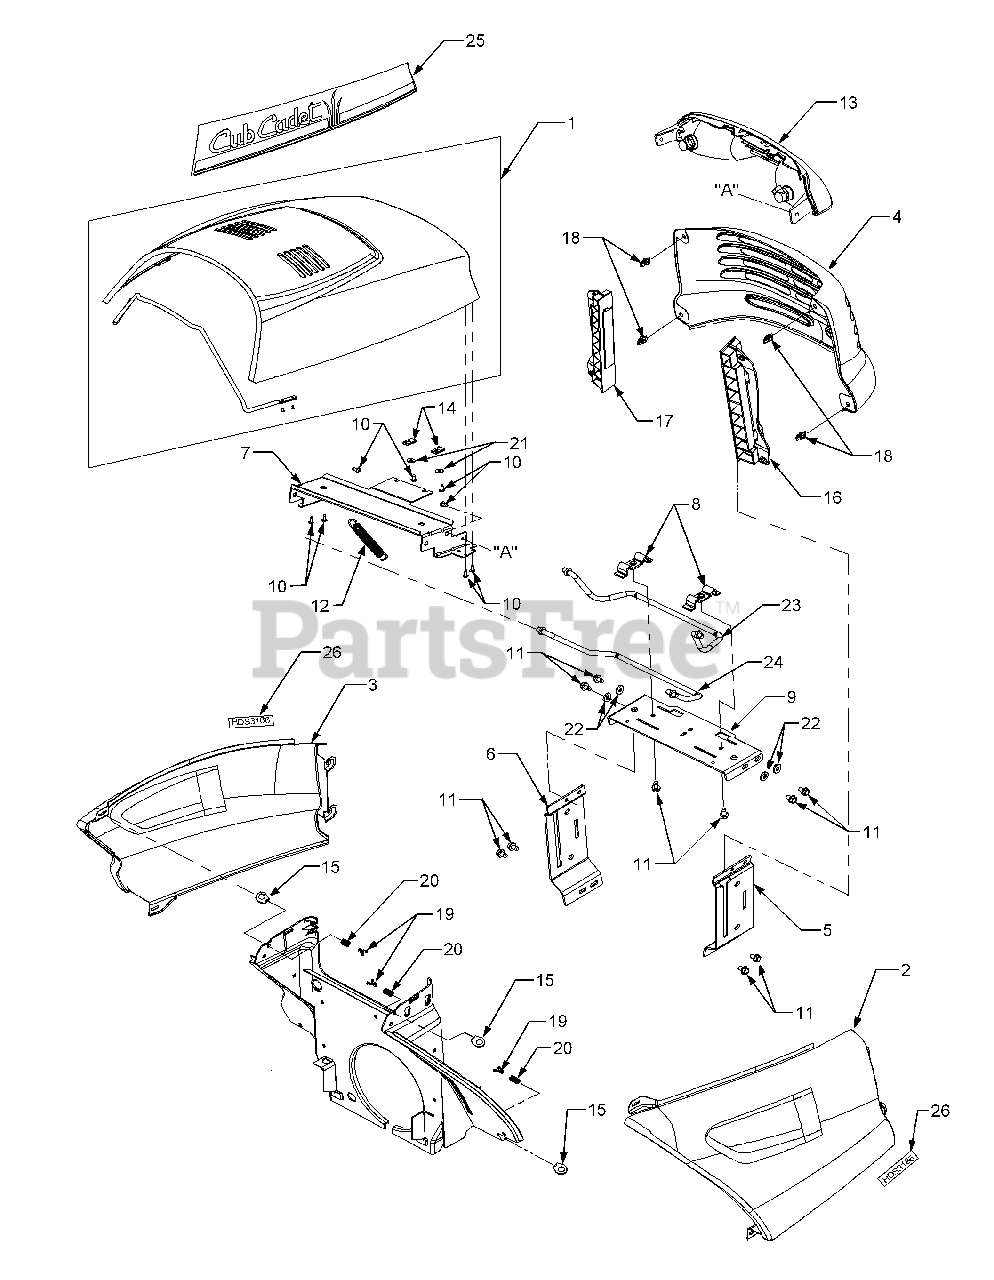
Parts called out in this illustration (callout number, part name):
1	Hood w/Support Rod Assembly
10	Screw, Truss Hd, Tapp, #10-16 x .5
11	Screw, Hex Wash. Hd. Tapp 5/16-18 x .5
12	Spring, Extension
13	Headlight Assembly
14	Nut, U-type Speed, #10
15	Latch, 1/4 Turn
16	Mount, Side Panel/Grille RH
17	Mount, Side Panel/Grille LH
18	Fastener, Grille Mount
19	Clip, Spring
20	Spring, Compression
21	Washer, Flat, .194 x .62 x .063
22	Washer, Flat, .344 x .75 x .120
23	Rod, Upper Hood
24	Rod, Upper Hood
25	Graphic, Hood - RH
26	Graphic, HDS 3186
